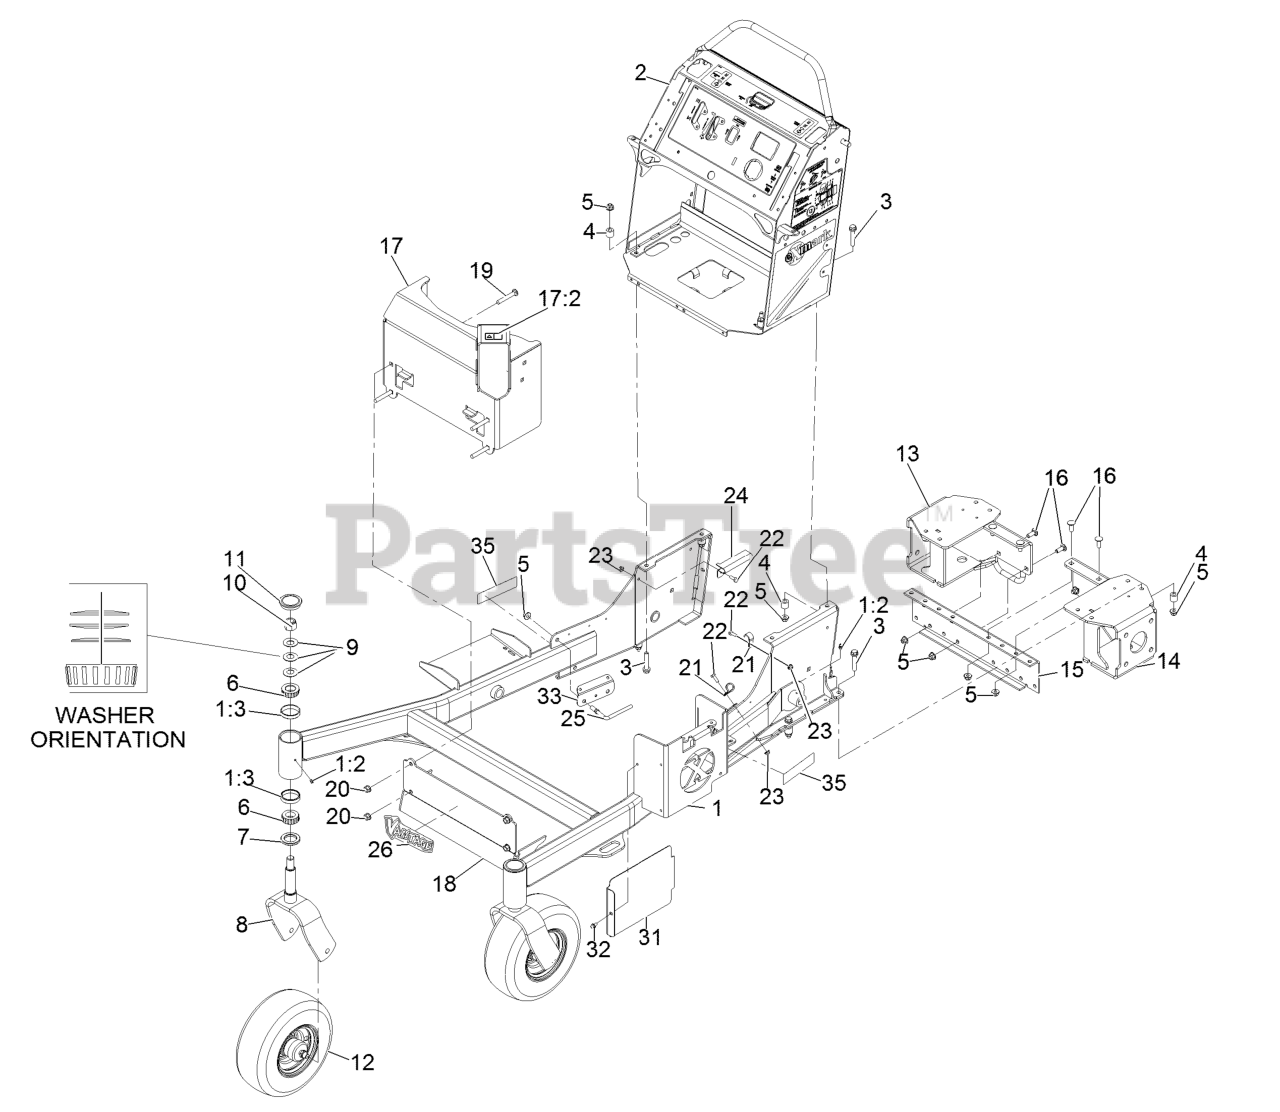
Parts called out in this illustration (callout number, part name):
1	FRONT FRAME ASM
1:2	FITTING-GREASE
2	CONTROL TOWER ASM-EFI
3	SCREW-HHF
5	NUT-HF, NI
6	Cone-Bearing Tapered Roller
7	SEAL-GREASE
8	FORK-CASTER
9	WASHER-BELLVILLE
10	NUT-LOCK, NI
11	CAP-GREASE
12	WHEEL/TIRE AND BEARING AS
13	RH MOTOR MOUNT ASM
14	LH MOTOR MOUNT ASM
15	MOUNT-MOTOR, CENTER
16	SCREW-CARR
17:2	DECAL-WARNING
18	PANEL-GUARD
19	SCREW-CARR
21	CLAMP-CABLE
22	SCREW-HH
24	BRACKET-HOSE, FUEL
25	GUIDE-HOSE, SUPPORT
26	DECAL-VANTAGE LOGO
31	SHIELD-HEAT, TALL
32	SCREW-HWH
33	GUARD-HOSE
35	DECAL-S-SERIES
